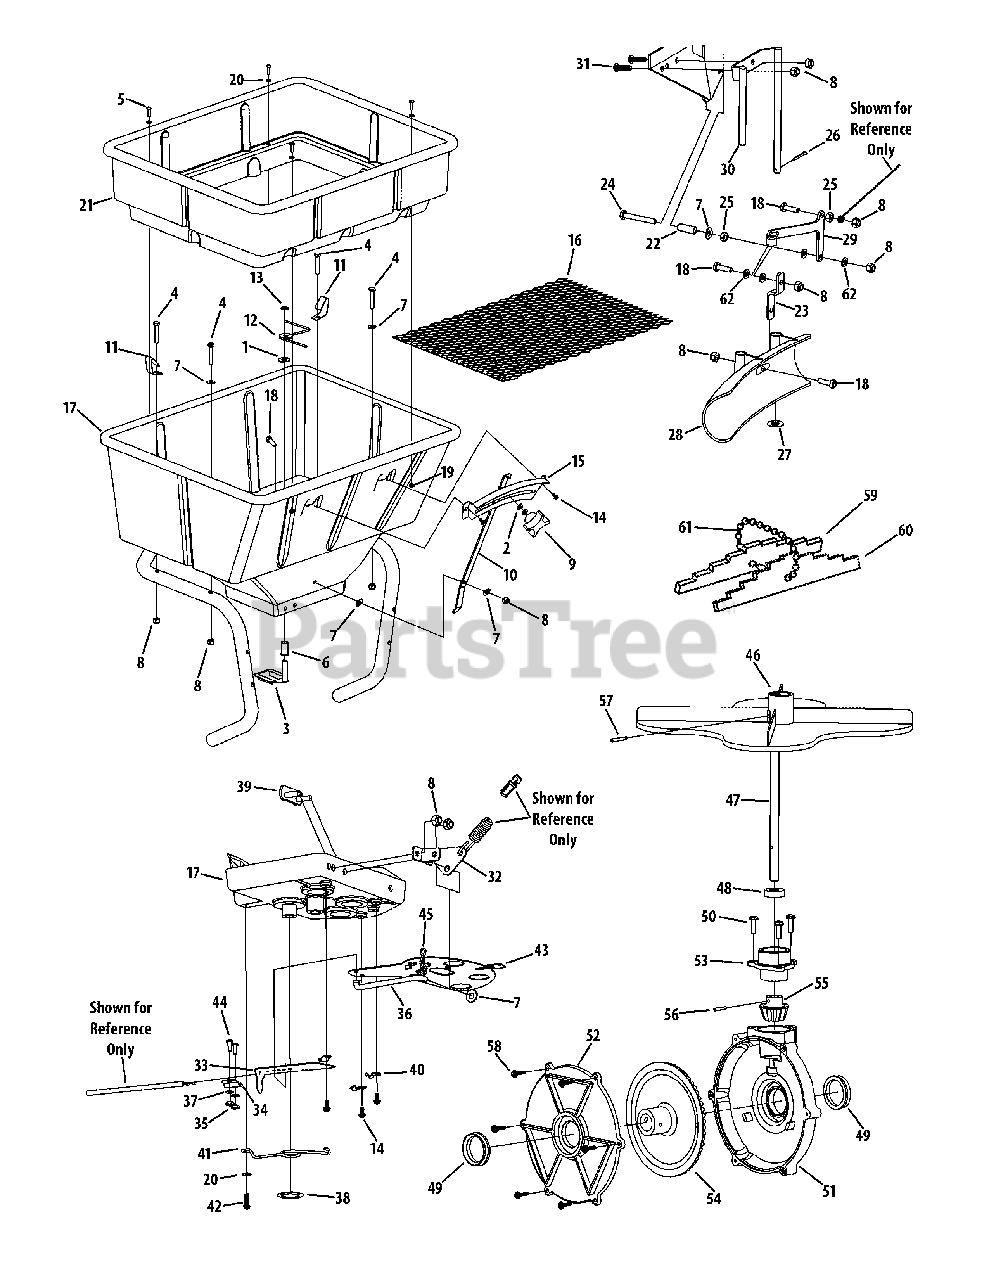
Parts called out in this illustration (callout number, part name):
1	Flat Washer, .406 x .812 x .062
2	Nylon Washer, 1/4
3	Agitator Cam Assembly
4	Hex Screw, 1/4-20 x 1.50
5	Hex Screw, 10-24 x 3/4
6	Agitator Bearing Shaft
7	Flat Washer, 1/4
8	Nut, 1/4-20
9	Control Rate Knob
10	Rate Control Arm
11	Screen Clip
12	Agitator Arm Assembly
13	Retainer Spring Clip, 3/8
14	Hex Washer Screw, #8 x 3/8
15	Numeric Rate Plate
16	Screen, 80-pound
17	80-pound Hopper Assembly
18	Machine Screw, 1/4-20 x 7/8
19	Nut, #10-24
20	Flat Washer, #8
21	80-pound Hopper Extension
22	Deflector Arm Mount Spacer
23	Offset Bracket Deflector
24	Machine Screw, 1/4-20 x 2
25	Nut, 1/4-20
26	Cotter Pin, 1/8 x 1
27	Flat Washer, 3/8
28	Deflector Tube
29	Bracket/Tube Mount Deflector Lever
30	Tube Mount Deflector Weldment
31	Socket Screw, 1/4-20 x .875
32	Electric Pivot Lever Assembly
33	Slide Lever
34	Remote 3rd-Hole Wire Bracket
35	Nut, 8-32
36	Pivot Lever Rod
37	Lock Washer, #8
38	Service Clip Spring
39	Two-Hole Plate Weldment
40	Shut-Off Plate Clip
41	Shut-Off Plate Spring
42	Hex Washer Screw, #8 x 5/8
43	Shut-Off Plate
44	Hex Screw, 8-32 x 1/2
45	Bow-Tie Cotter Pin
47	Impeller Shaft
48	Oil Gearset Seal
49	V Gearset Seal
50	Screw, #10
51	Gearset Housing
52	Gearset Cover
53	Gearset Cap
54	Gearset Bevel Gear
55	Pinion Gearbox Gear
56	Roller Pin, 1/8 x 5/8
57	Roller Pin, 1/8 x 7/8
58	Hex Washer Screw, #6 x 5/8
59	Calibration Gauge, Odd
60	Calibration Gauge, Even
61	Calibration Gauge Chain
62	Nylon Washer, 1/4
